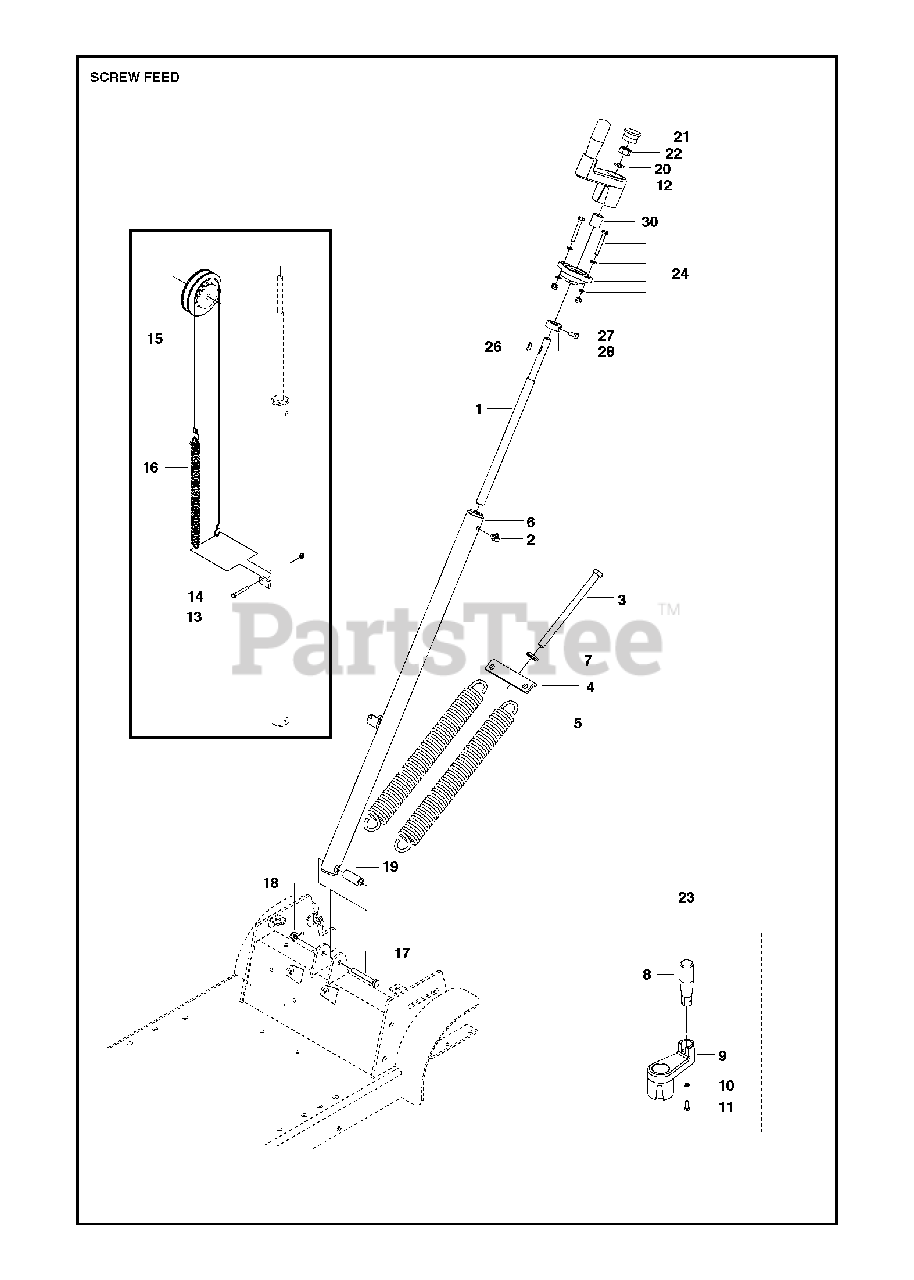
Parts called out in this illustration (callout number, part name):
7	WASHER
10	WASHER
13	HEXAGON LOCKING NUT
18	HEXAGON LOCKING NUT
20	WASHER
